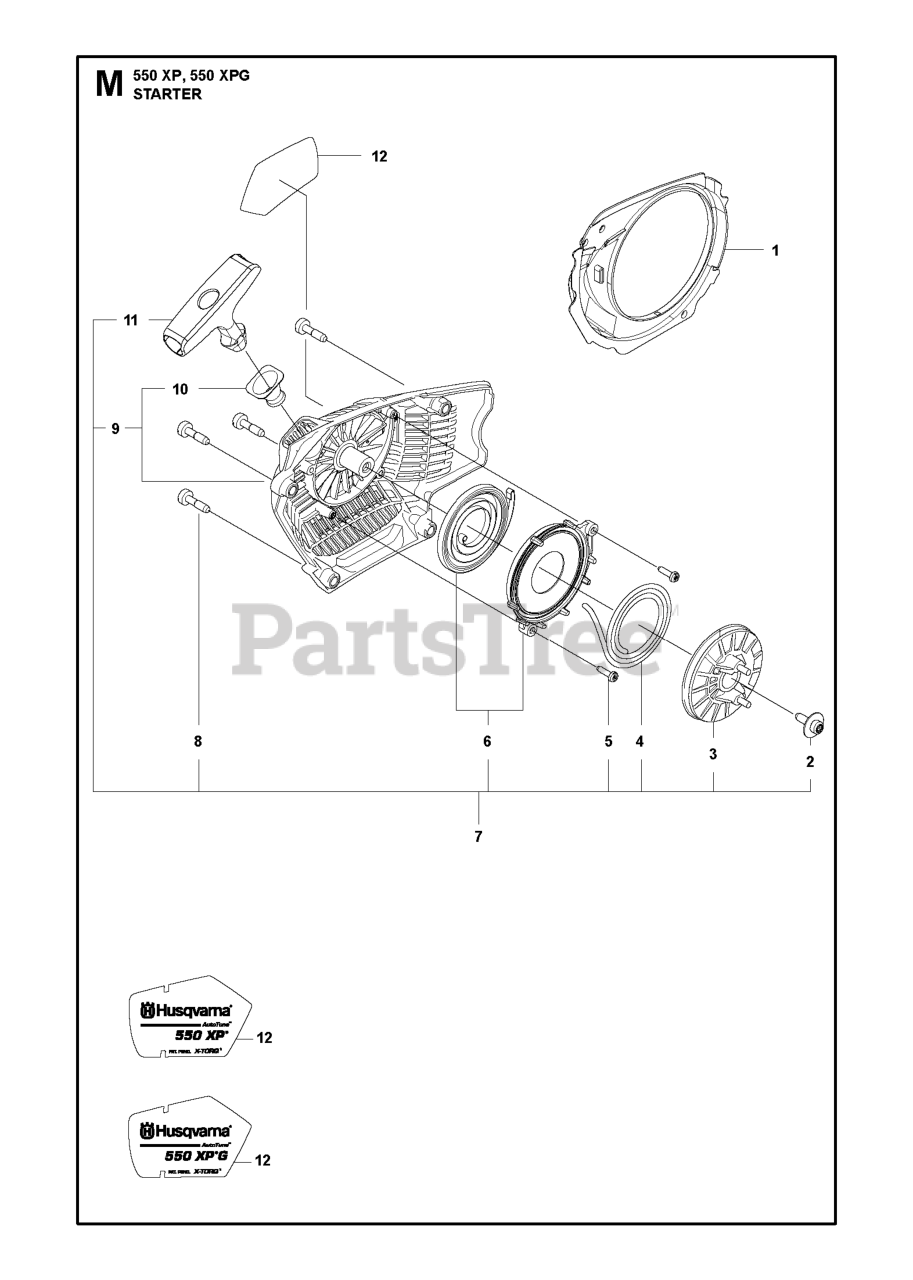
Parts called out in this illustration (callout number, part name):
1	COOLING AIR CONDUCTOR
2	SCREW ITXSCT MT5X16 10.9 TBO
3	STARTER PULLEY ASSY
4	STARTER ROPE
5	SCREW CITXPANT
6	SPRING CASSETTE ASSY
7	STARTER ASSY
8	SCREW CITXPANMO
9	STARTER HOUSING ASSY
12	LABEL
